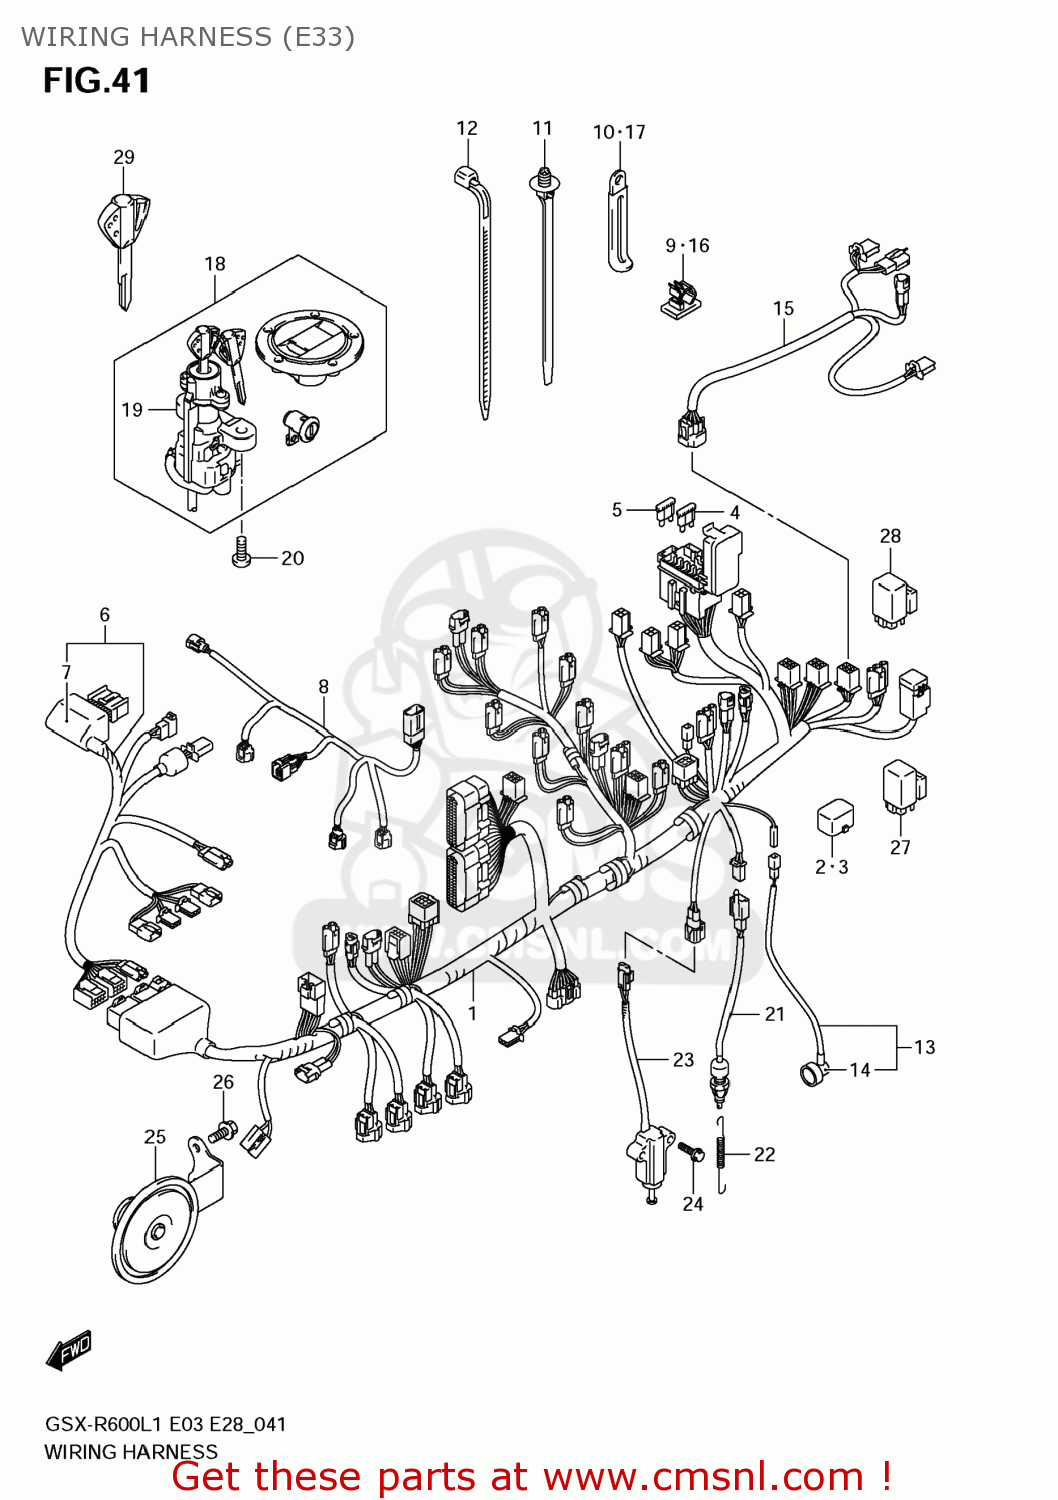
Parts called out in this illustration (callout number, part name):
1	HARNESS,WIRING NO.1
2	CAP,TS
3	CAP,CO ADJUST
4	FUSE(10A)
5	FUSE(15A)
6	HARNESS,WIRING NO.2
7	COVER,CONNECTOR
8	HARNESS,WIRING NO.3
9	CLAMP(L:95)
10	CLAMP(L:145)
11	CLAMP(L:154)
12	CLAMP(L:125)
13	WIRE,OIL PRESSURE SWITCH LEAD
14	CAP,OIL PRESSURE SWITCH
15	WIRE,RR COMB LEAD
16	CLAMP
17	CLAMP(L:45)
18	LOCK SET
19	LOCK ASSY,STEERING
20	BOLT(8X20)
21	SWITCH ASSY,STOP LAMP
22	SPRING
23	SWITCH ASSY,SIDE STAND
24	BOLT
25	HORN ASSY
26	BOLT
27	RELAY ASSY
28	RELAY ASSY
29	KEY,BLANK(IMMOBII)
